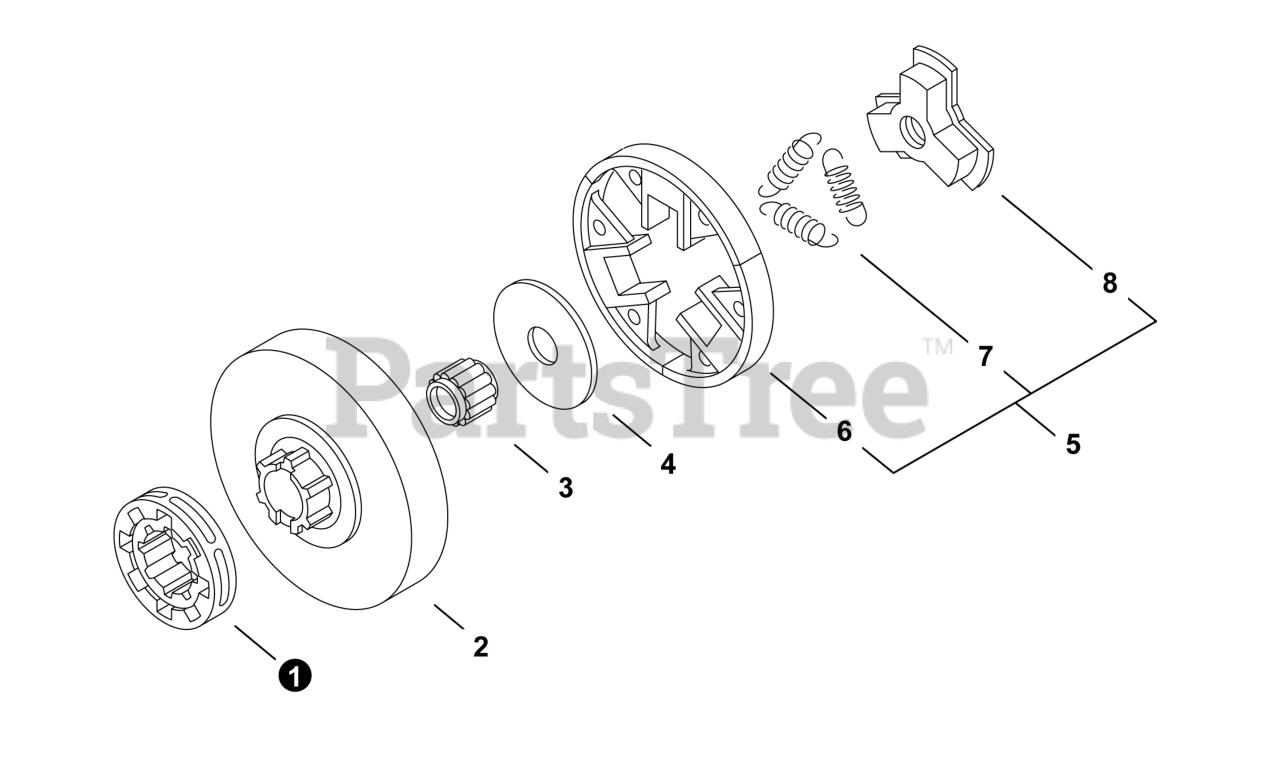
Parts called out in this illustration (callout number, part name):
1	SPROCKET, RIM 3/8"×7T
2	DRUM, CLUTCH
3	BEARING, NEEDLE
4	PLATE, CLUTCH
5	CLUTCH ASSY
6	SHOE SET, CLUTCH (3PCS)
7	SPRING, TENSION
8	HUB, CLUTCH
